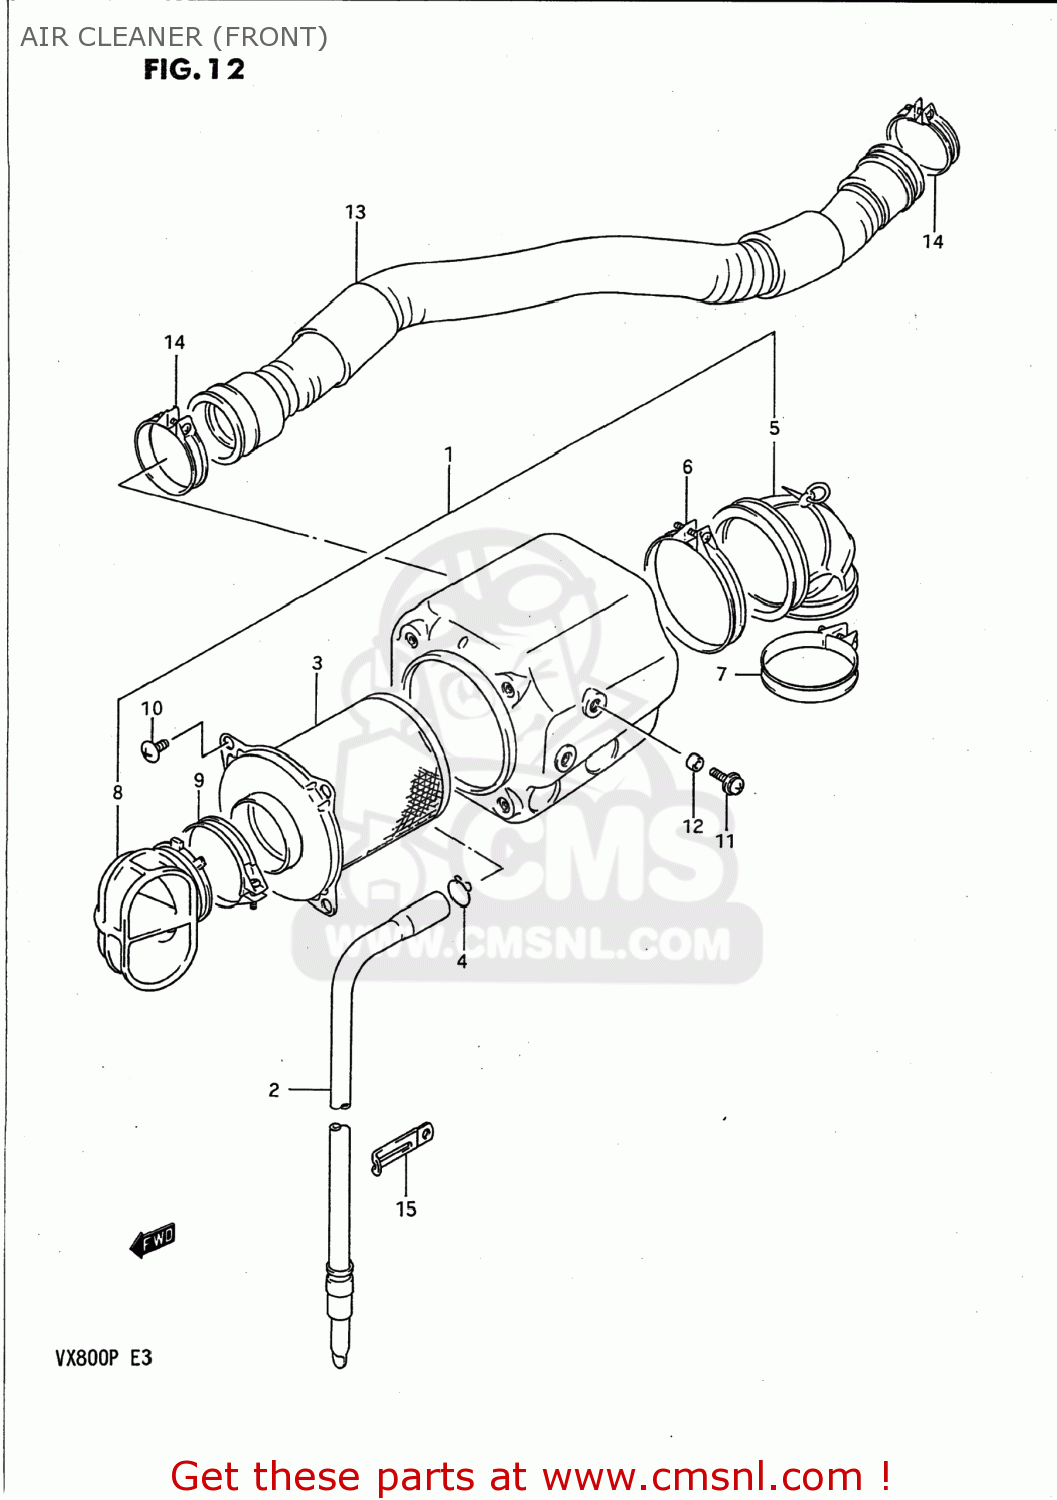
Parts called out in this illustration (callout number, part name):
1	CLEANER ASSEMBLY,AIR,FRONT
2	TUBE,DRAIN
3	FILTER ASSY,AIR
4	CLIP
5	TUBE,AIR CLEANER OUTLET
6	CLAMP
7	CLAMP
8	TUBE,INLET
9	CLAMP
10	SCREW
11	SCREW
12	SPACER(6.2X8.3X6.1)
13	HOSE,AIR CLEANER
14	CLAMP
15	CLAMP
